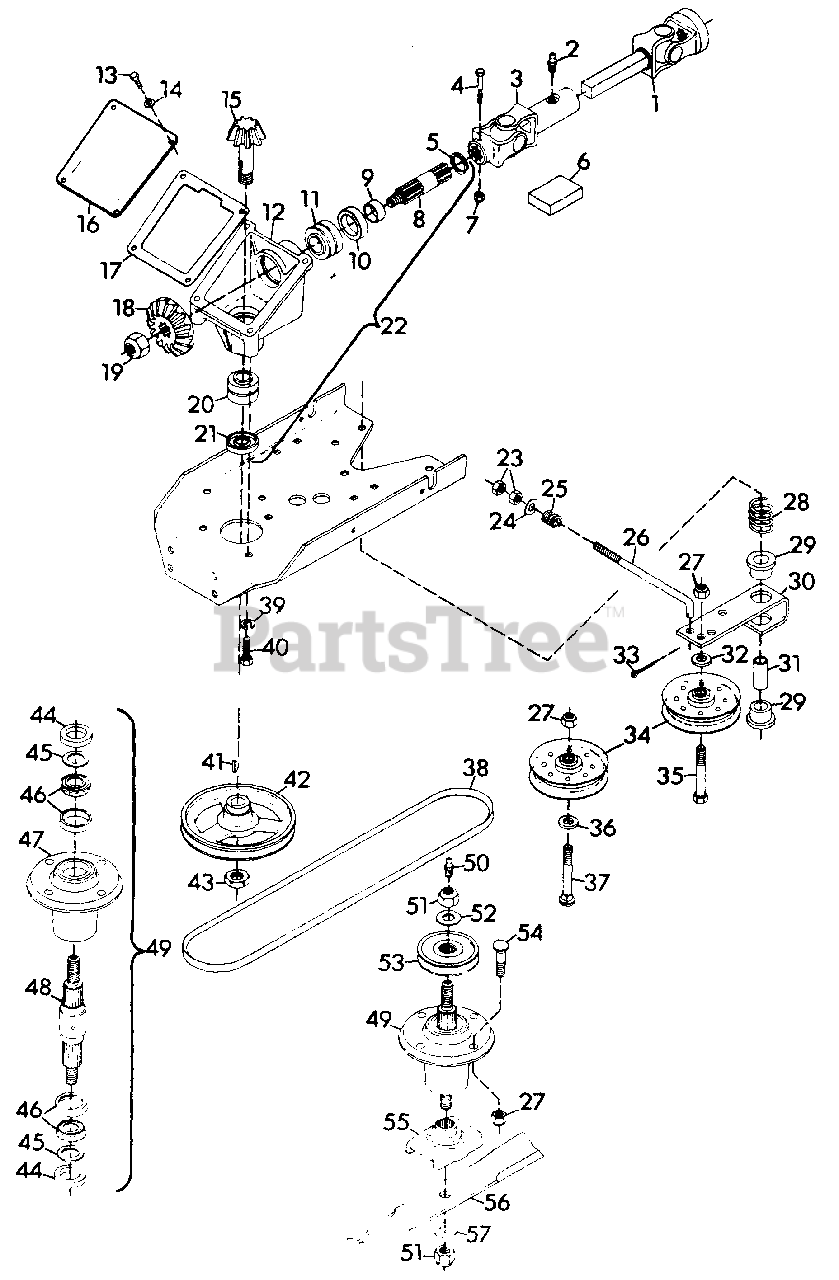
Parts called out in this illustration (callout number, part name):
1	SHAFT, PROP. SQ. BAR
2	FITTING, LUBE 1/4-28
3	U-JOINT, FEMALE END
4	BOLT, HEX 1/4-20X2
5	RING, RETAINING 1.000 SHAFT
6	KIT, REPAIR UNIVERSAL JOINT ROCKWELL STD.
6	KIT, REPAIR UNIVERSAL JOINT NEAPCO 1605X
7	NUT, LOCK 1/4-20
8	SHAFT, DRIVE
9	SPACER
10	SEAL, OIL 1.25X1.987X.250
11	ASSEMBLY, BEARING 1.000X1.980X1.243
12	CASTING, GEAR BOX
13	BOLT, HEX 1/4-20X.50
14	WASHER, LOCK 1/4
15	SHAFT, GEAR PINION
16	COVER, GEAR HOUSING
17	GASKET, GEAR HOUSING
18	GEAR, BEVEL
19	NUT, LOCK 3/4-10
20	ASSEMBLY, BEARING .750X1.781X1.499
21	SEAL, OIL 1.250X1.686X.313
22	ASSEMBLY, DRIVE 50" MOWER
23	NUT, HEX 3/8-24
24	WASHER, FLAT .406X.812X.065
25	SPRING, COMP. TYPE 1X.78X338 LB/IN
26	ROD, IDLER
27	NUT, LOCK 3/8-16
28	SPRING, COMP.
29	BUSHING, NYLON .760X1.00X.600
30	ARM, IDLER PIVOT
31	SPACER
32	SPACER, IDLER .406X.750X.188
33	PIN, COTTER 3/32X1.00
34	SHEAVE, IDLER
35	BOLT, HEX 3/8-16X2
36	WASHER, FLAT .438X1.000X.083
37	BOLT, 3/8-16X1.75 RD HD SQ NK
38	BELT, V .500X.312X126.3
39	WASHER, LOCK 1/2
40	BOLT, HEX 1/2-13X1.00
41	KEY, WOODRUFF .188X.625 HARD
42	SHEAVE, 1/2X6.50
43	NUT, JAM 3/4-10 HEX HEAVY
44	SEAL, STEEL
45	WASHER, FLAT .975X1.970X.030
46	ASSEMBLY, BEARING
47	HOUSING, BEARING
48	SHAFT, SPINDLE
49	ASSEMBLY, SPINDLE
50	FITTING, LUBE 1/8(LEFT AND RIGHT SPINDLE)
50	FITTING, LUBE .125 EXT.(CENTER SPINDLE)
51	NUT, LOCK 5/8-11
52	WASHER, FLAT .687X1.312X.122/.146
53	SHEAVE, SPINDLE
54	BOLT, 3/8-16X1.25 RD HD SQ NK
55	CRADLE, BLADE
56	BLADE
57	WASHER, FLAT .656X1.312X.095
